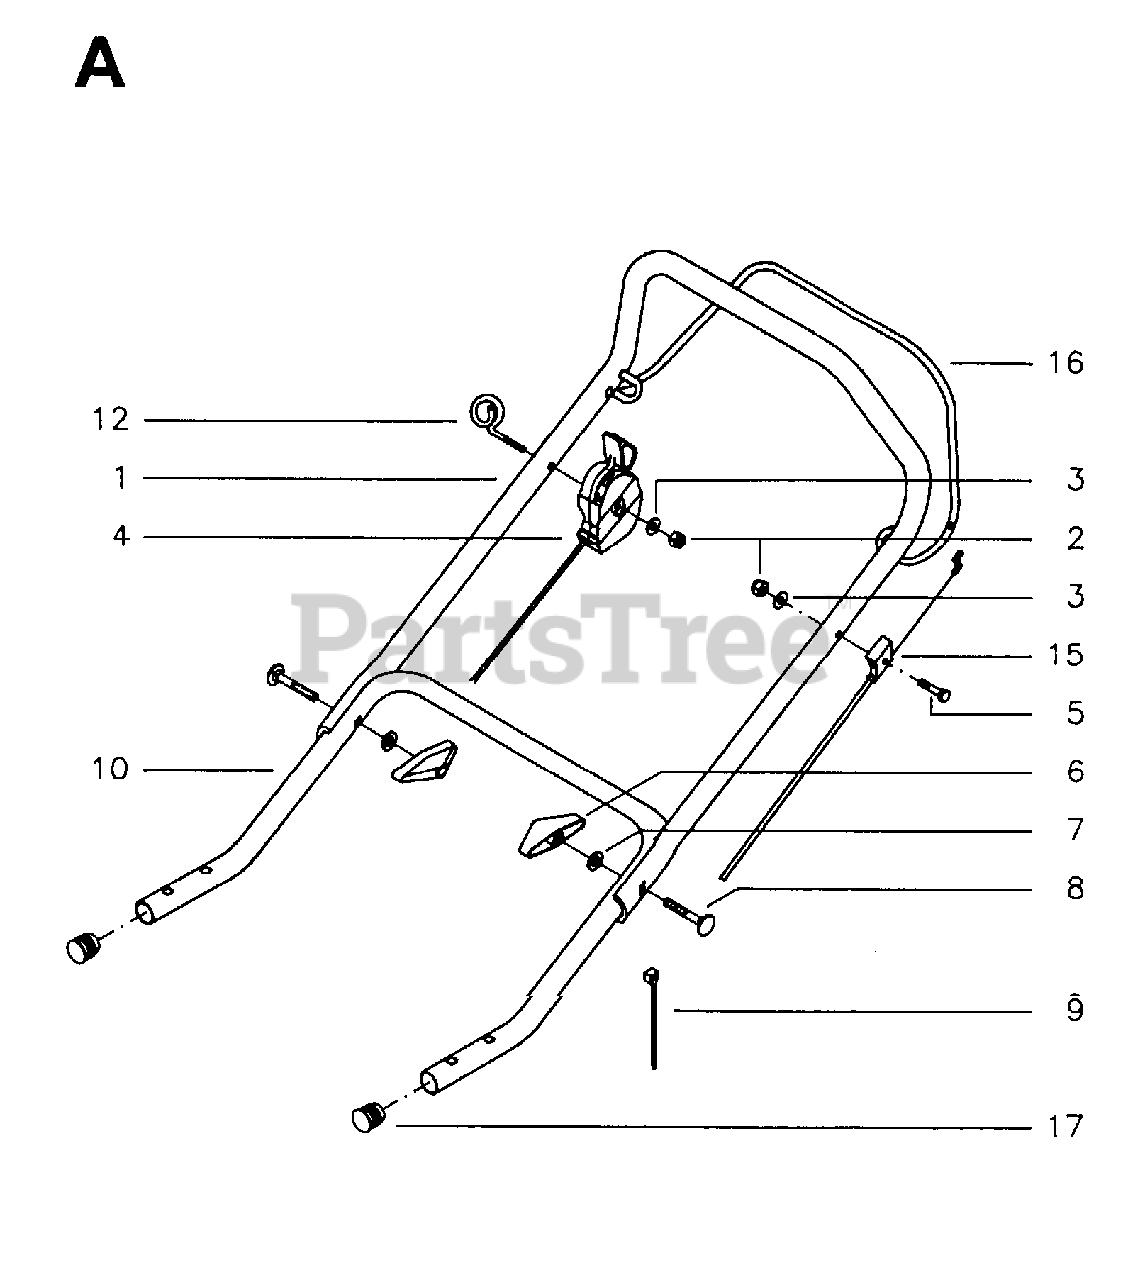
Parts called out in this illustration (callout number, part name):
2	LOCKNUT M6
4	THROTTLE TRIGGER
5	BOLT FLANGE
